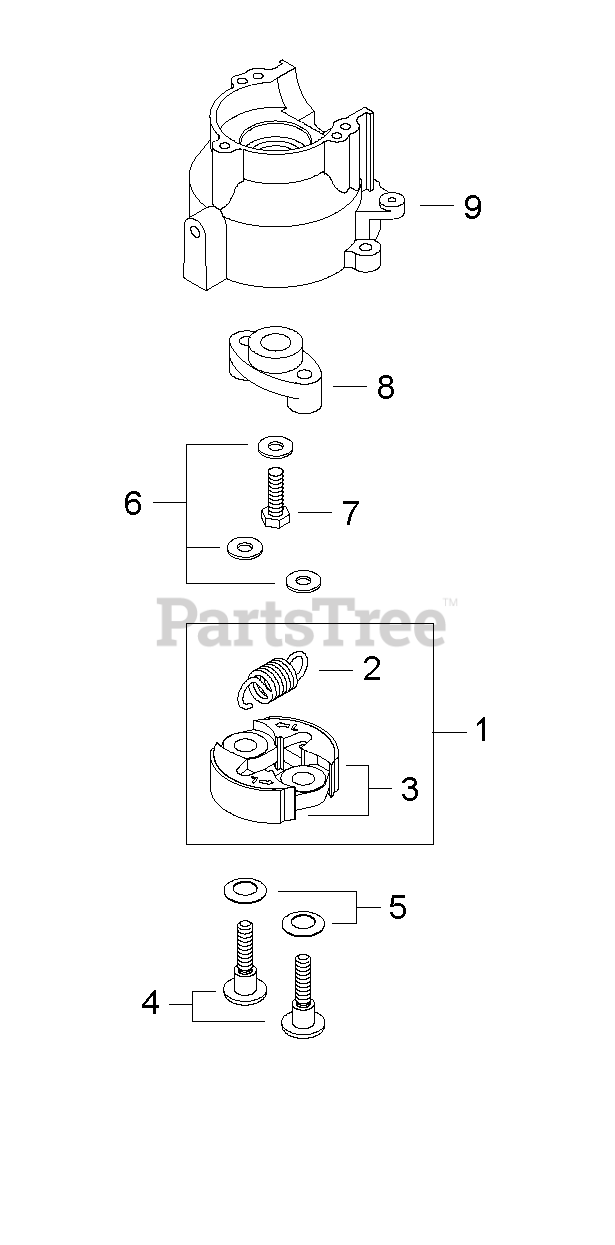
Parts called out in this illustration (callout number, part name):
1	SHOE ASSY, CLUTCH
2	SPRING, CLUTCH
3	SHOE, CLUTCH
4	BOLT, CLUTCH
5	WASHER, SPRING
6	WASHER 6 MM
7	BOLT M6×18
8	BOSS, CLUTCH
9	CRANKCASE ASSY, PTO
